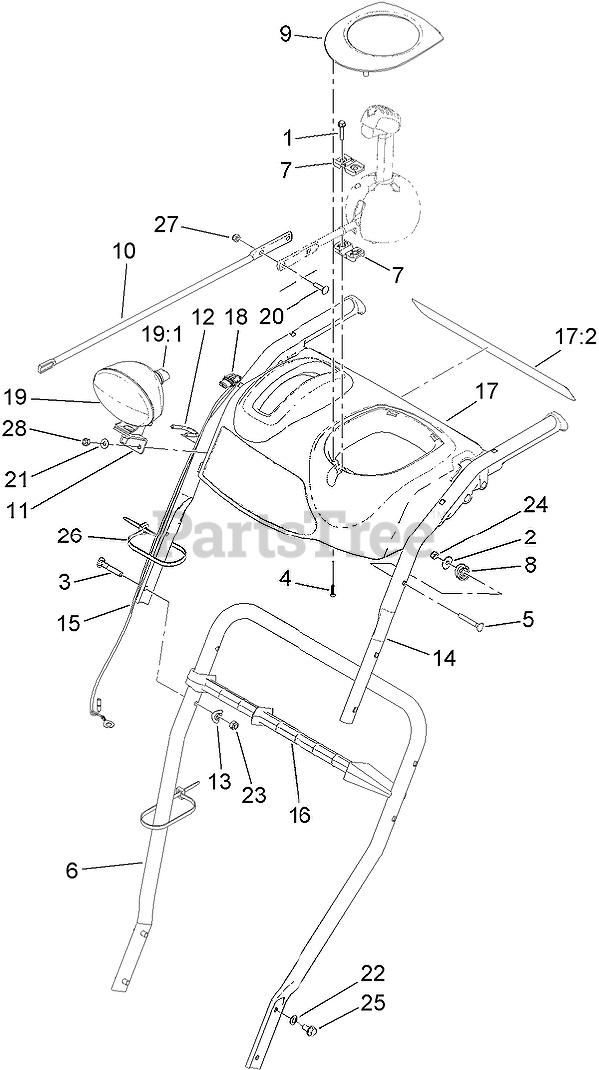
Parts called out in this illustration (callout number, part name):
1	SCREW-PLASTITE
2	WASHER-PLAIN
3	SCREW-HANDLE
4	SCREW-PPH
5	SCREW
6	HANDLE-LOWER
7	SUPPORT-ROD
8	CLAMP-CABLE
9	COVER-PANEL, CONTROL
10	ROD-CHUTE, FRONT
11	BRACKET-LIGHT
12	CLAMP
13	WASHER
14	HANDLE-UPPER, LH
15	HANDLE-UPPER, RH
16	STICK-CLEANOUT
17	PANEL-CONTROL
17:2	DECAL-WARNING
18	HARNESS-WIRE
19	HEADLAMP ASM
19:1	LAMP-12 VOLT
20	SCREW-CARR
21	WASHER-FLAT
22	WASHER-BELLEVILLE
23	NUT-LOCK, NI
24	NUT-LOCK, NI
25	SCREW-HWHTF
26	TIE-CABLE
27	NUT-LOCK, NI
28	NUT-LOCK, NI
